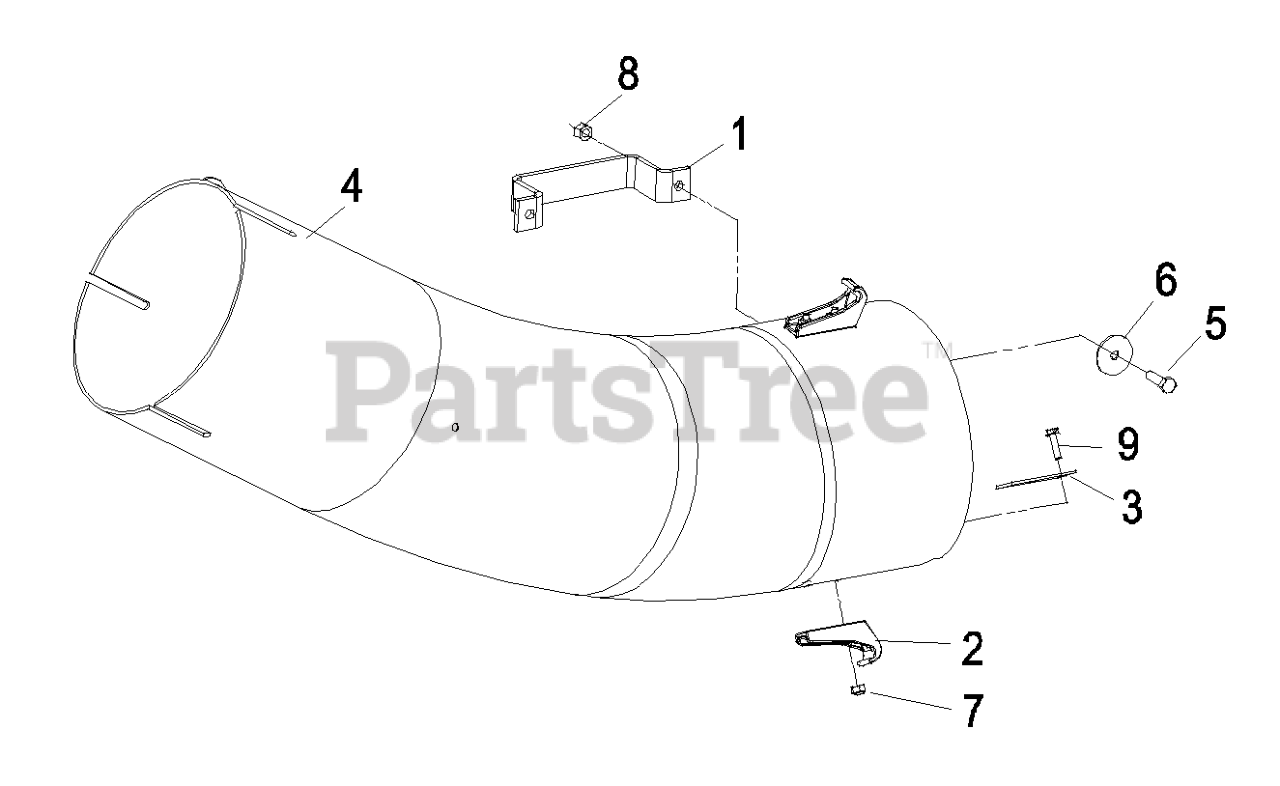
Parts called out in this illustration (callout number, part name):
2	LATCH-CATCH
3	PLATE-BACKING
4	TUBE-LOWER
5	SCREW-HH
6	WASHER-FLAT
7	NUT-LOCK, NI
8	NUT-LOCK, NI
9	SCREW-HWH
